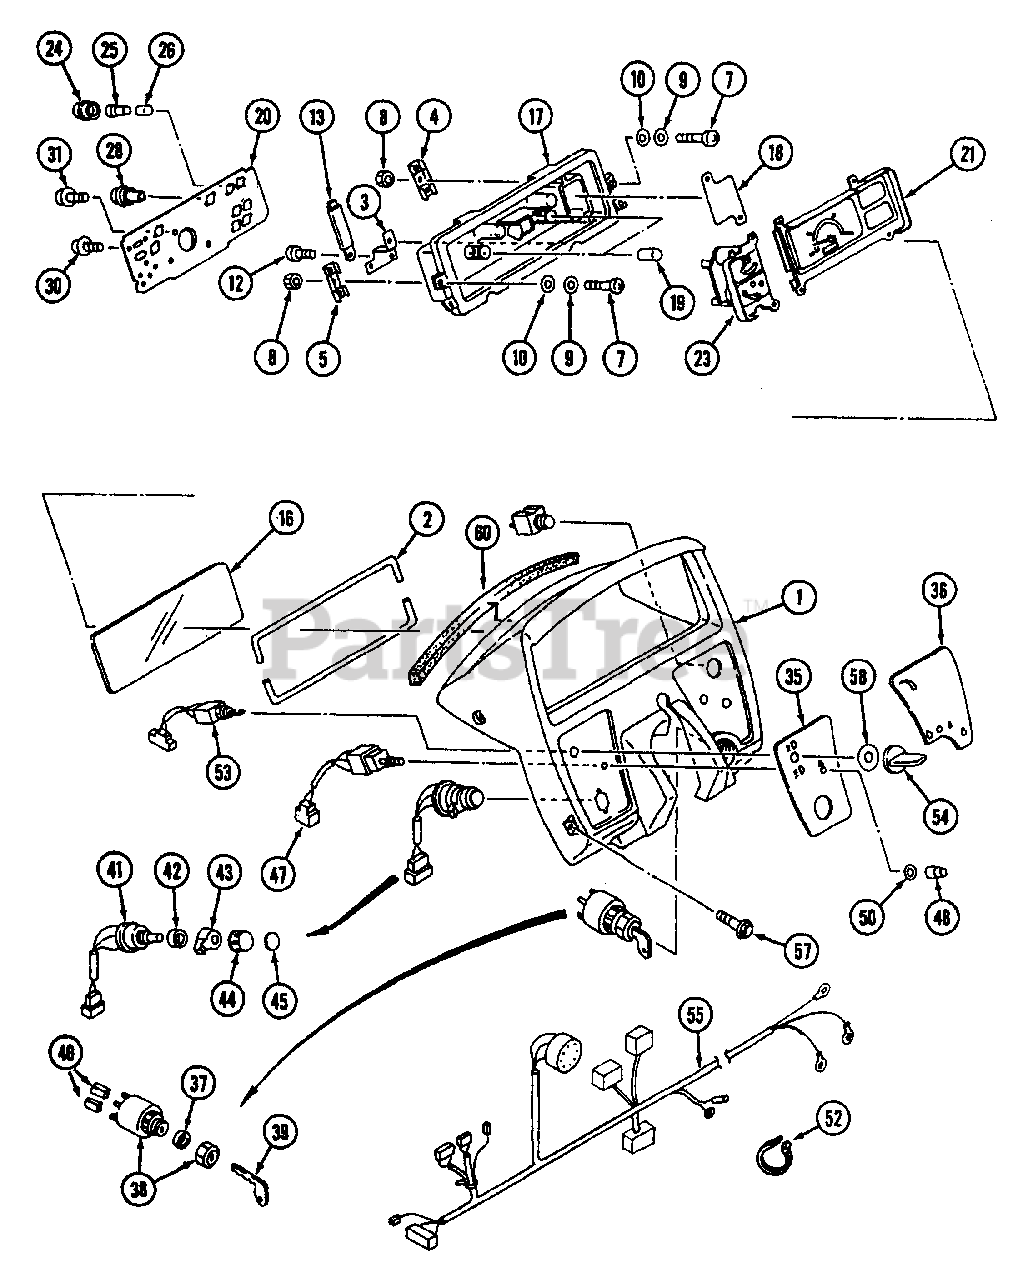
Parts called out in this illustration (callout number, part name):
16	Glass Ass'y
18	Plate Monitor
19	Lens Indicator
20	Board,Print
23	Meter Fuel & Temp.
35	Label, Panel L.H
36	Label,Panel R.H
37	Packing Starter
38	Switch Starter
39	Key,Starter
41	Switchbody Ass'y.
42	Ring Nut
43	Flasher Lever
44	Lighting Knob
53	Switch,Light H/L
58	Packing Rubber
